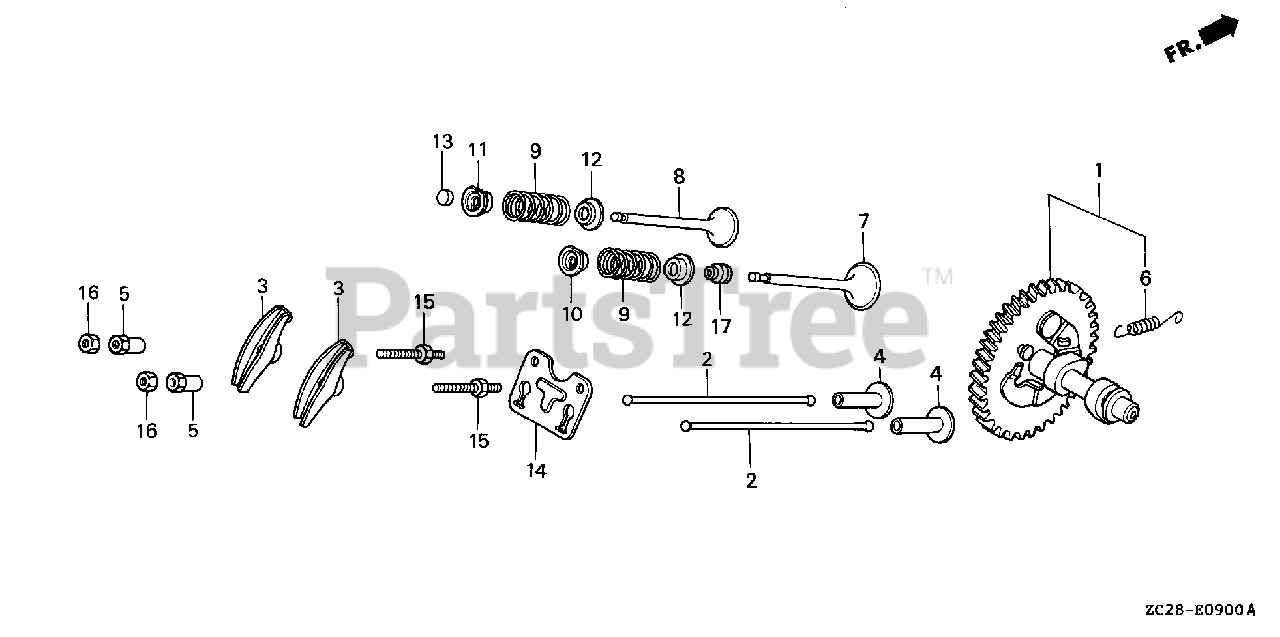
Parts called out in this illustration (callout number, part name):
1	CAMSHAFT ASSY.
2	ROD, PUSH
3	ARM, VALVE ROCKER
4	LIFTER, VALVE
5	PIVOT, ROCKER ARM
6	SPRING, WEIGHT RETURN
7	VALVE, IN.
8	VALVE, EX. (STELITE)
9	SPRING, VALVE
10	RETAINER, IN. VALVE SPRING
11	RETAINER, EX. VALVE SPRING
12	SEAT, VALVE SPRING
13	ROTATOR, VALVE
14	PLATE, PUSH ROD GUIDE
15	BOLT, PIVOT (8MM)
16	NUT, PIVOT ADJ.
17	SEAL, VALVE STEM
